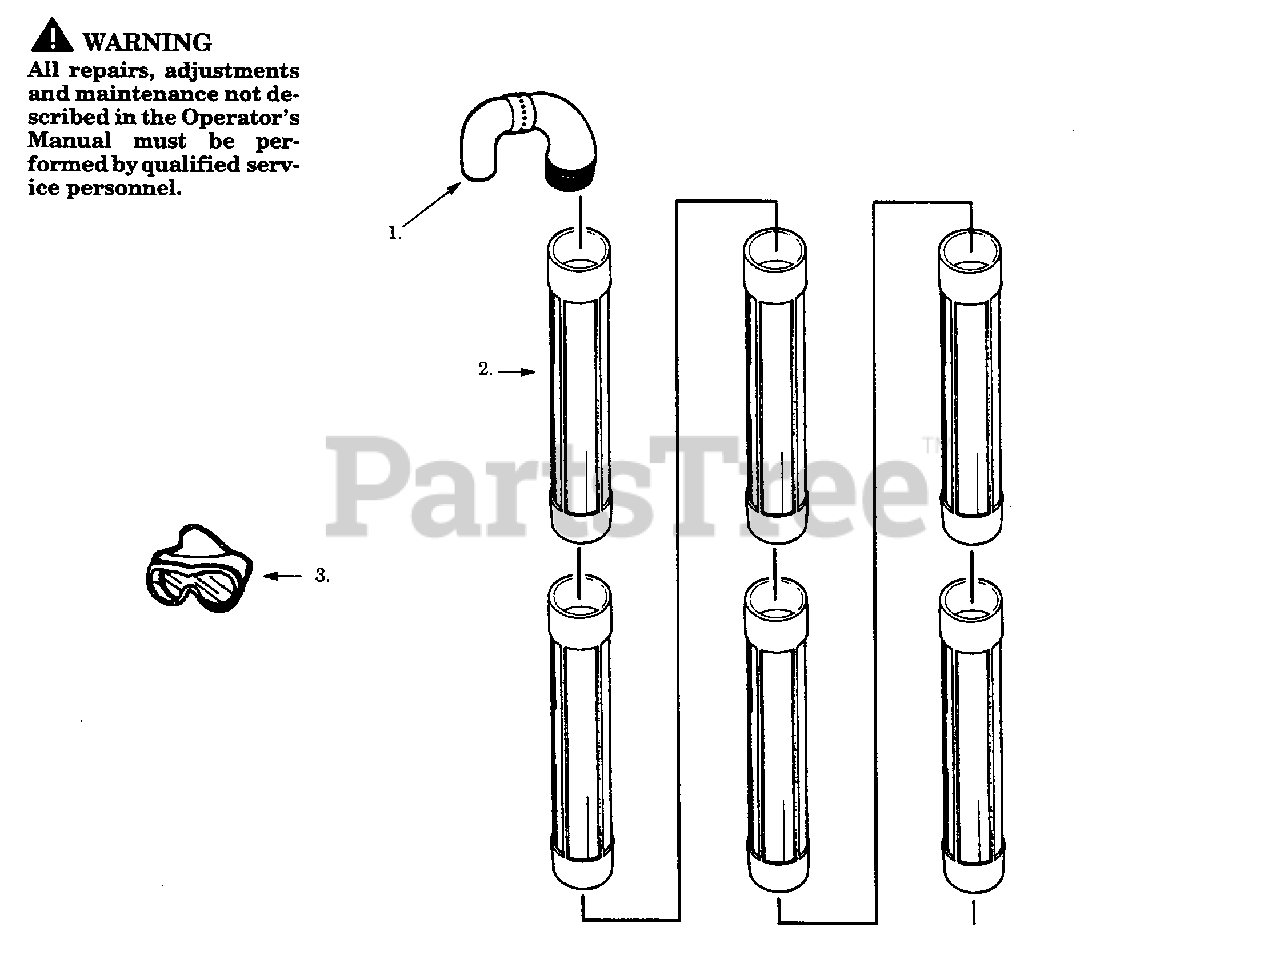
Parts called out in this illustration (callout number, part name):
1	Nozzle Ass'y.
2	Outlet Tube (1 of 6)
3	Safety Goggles
